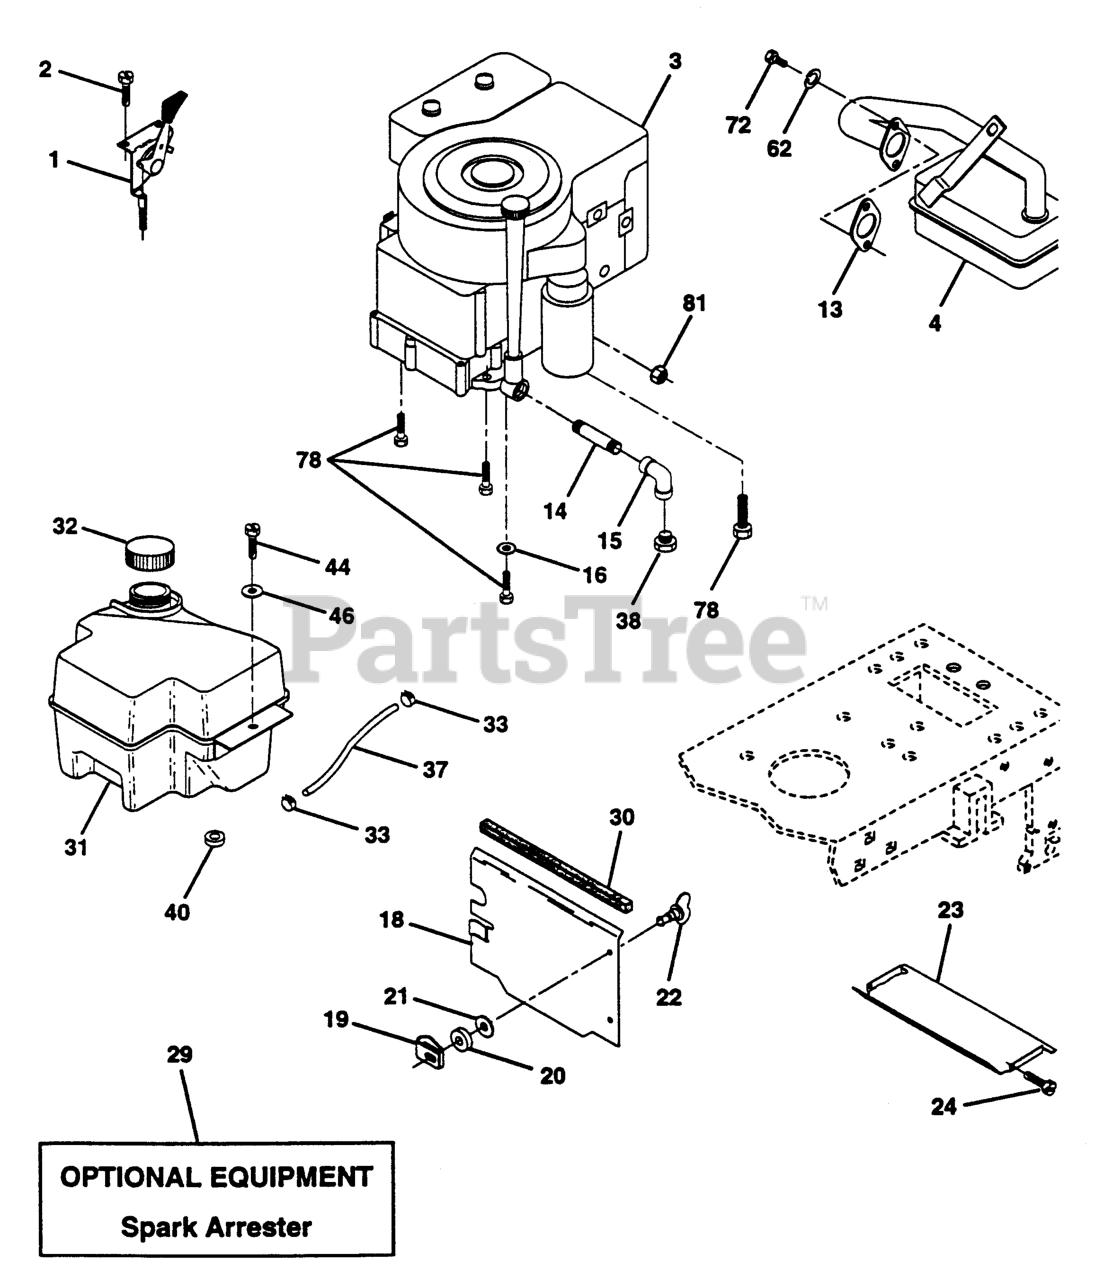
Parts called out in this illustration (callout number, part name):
1	CHOKE CONTROL
2	SCREW LT
4	MUFFLER.SINGLE.B&S.10-12HP
13	GASKET ENGINE
14	Nipple Pipe 3/8 Npt X 3"
15	ELBOW
16	LOCKWASHER
18	HEAT SHIELD
19	RECEPTACLE LT
20	RETAINER LT
21	WASHER
22	STUD 1/4 TURN
23	HEAT SHIELD
29	KIT.SPARK ARRESTOR 794945 B&S
31	FUEL TANK
32	FUEL CAP
33	HOSE CLAMP
37	LINE.FUEL.20
38	Plug Oil Drain
40	BUSHING.SNAP.NYL.BLK.
44	SCREW HEX CRT
46	WASHER
62	WASHER.LOCK.HVY.HLCL.SPR.5/16
72	SCREW
78	SCREW
81	NUT
